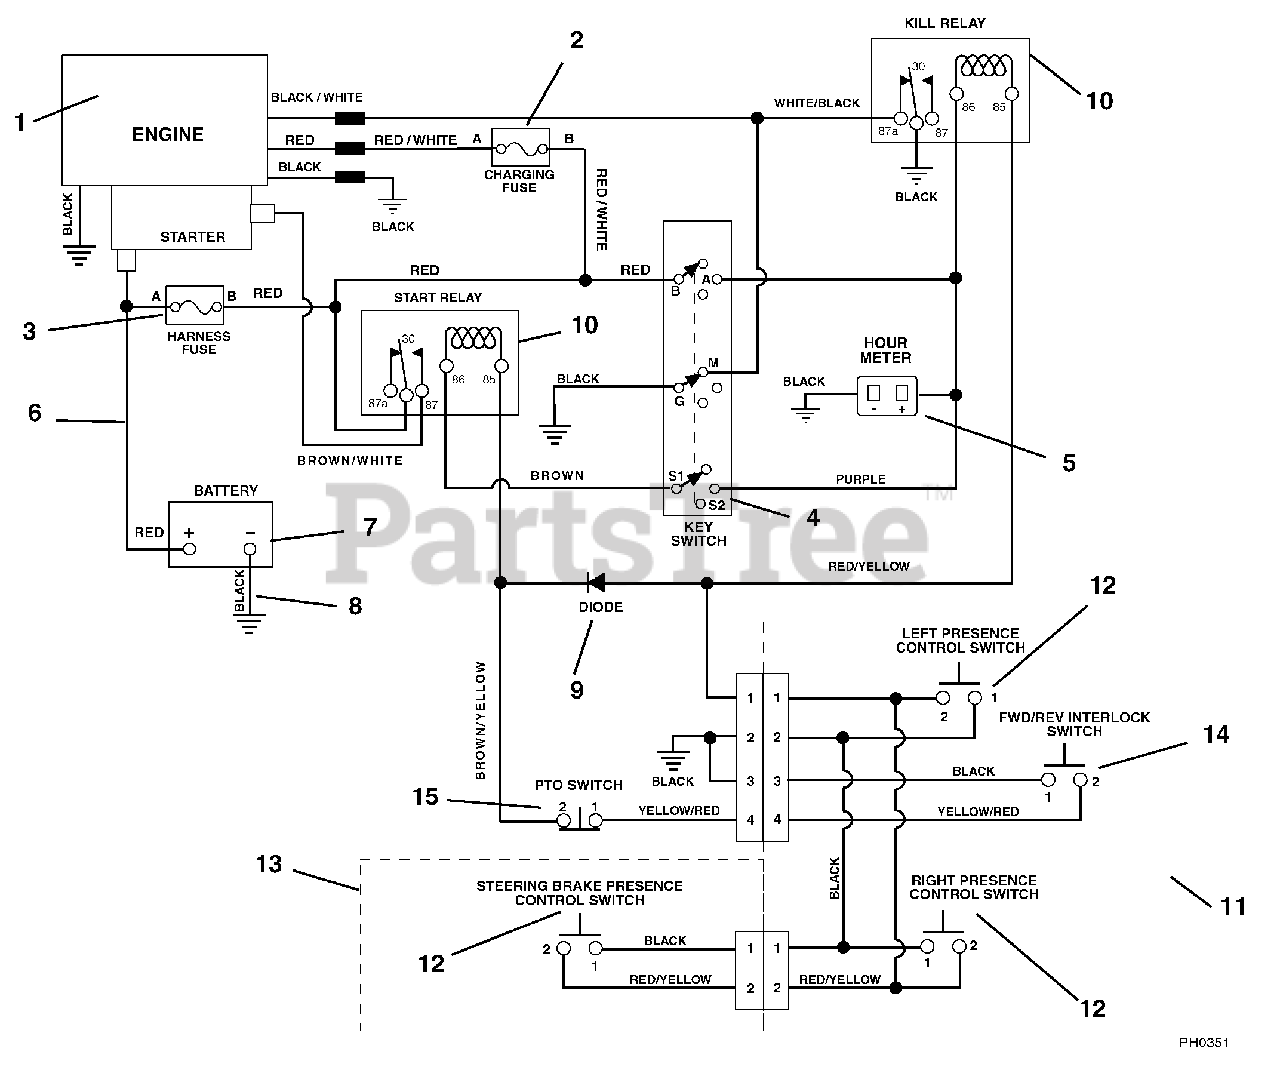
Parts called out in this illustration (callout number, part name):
1	Engine, Kohler Command Pro CS12ST (119)
2	Fuse 15 AMP
3	Fuse 20 AMP
4	Key Switch
5	Hour Meter
6	Start Cable 22"
8	Cable, Negative Battery 35"
9	Molded Diode Plug- Clear 1 AMP
10	Relay
11	Harness, Handlebar
12	Switch
13	Harness, Steering Brake
14	Switch, Interlock Closed (Forward/Reverse)
15	Switch, Interlock Open (PTO)
